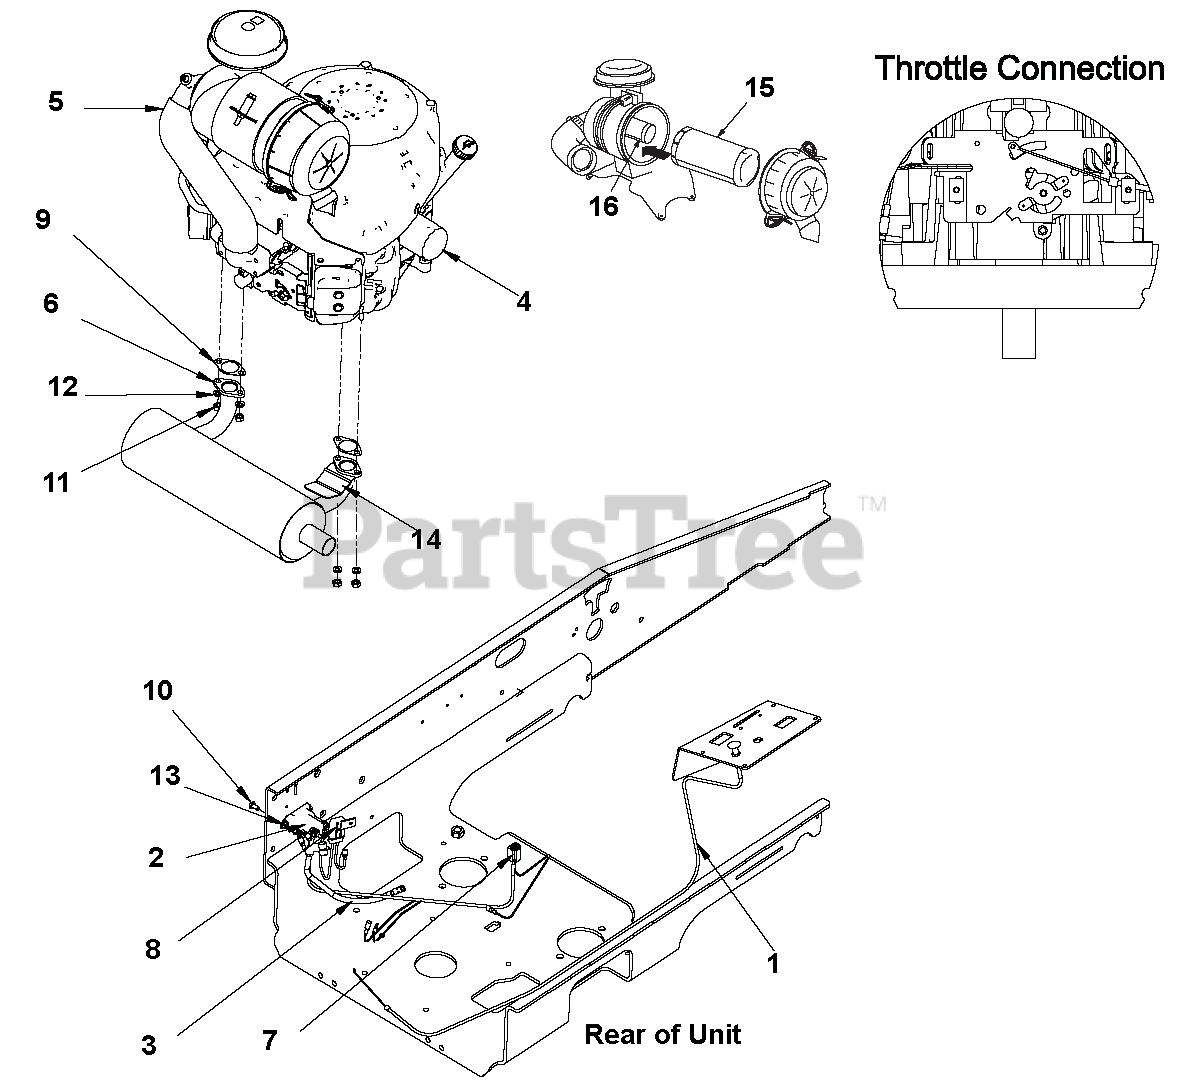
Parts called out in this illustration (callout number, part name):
1	CABLE, CHOKE 48.0"
2	SOLENOID
3	STARTER CABLE
4	OIL FILTER S/O
5	ENGINE, KAWASAKI 19HP FH580V
6	MUFFLER, KAWASAKI FH-HORI
7	ADAPTER HARNESS, 19KAI/23KAW
8	ADAPTER HARNESS KAWASAKI, FUSE
9	GASKET KIT, INCLUDES ITEMS 2,8
10	@BLT-HEX .25-20X.50 GR5 YWZC
11	NUT, M8X1.25 HEX GR8.8 Y
12	WASHER, M8 SPRG LOCK Y
13	@NUT-SPNLK-FLG .25-20 YWZC
14	SHIELD, HEAT
15	AIR FILTER PRIMARY S/O
16	AIR FILTER SECONDARY S/O
